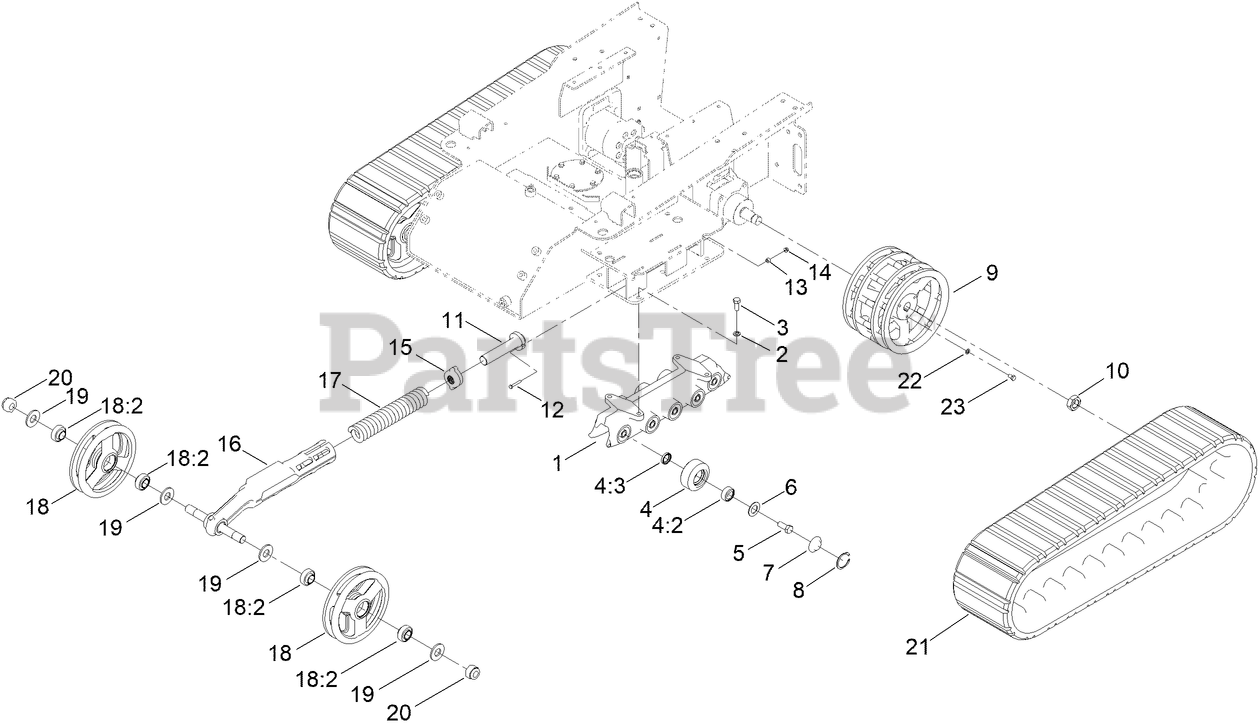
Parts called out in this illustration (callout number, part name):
1	GUIDE-TRACK, TX WIDE
2	WASHER-LOCK
3	SCREW-HH
4	ROAD WHEEL ASM
4:2	BEARING-BALL
4:3	SEAL-OIL
5	SCREW-HH
6	GASKET-BOGIE
7	CAP-WHEEL, BEARING
8	RING-SNAP, INTERNAL
9	WHEEL-DRIVE
10	NUT-HEX
11	BOLT-TENSIONER
12	SCREW-HH
13	SPACER
14	NUT-HHF
15	BLOCK-TENSIONER
16	ARM-TENSIONER
17	SPRING-COMPRESSION
18	TENSIONER WHEEL ASM
18:2	BEARING-BALL
19	WASHER-PLAIN
20	NUT-HEX, NI
22	WASHER-LOCK
23	SCREW-HH
